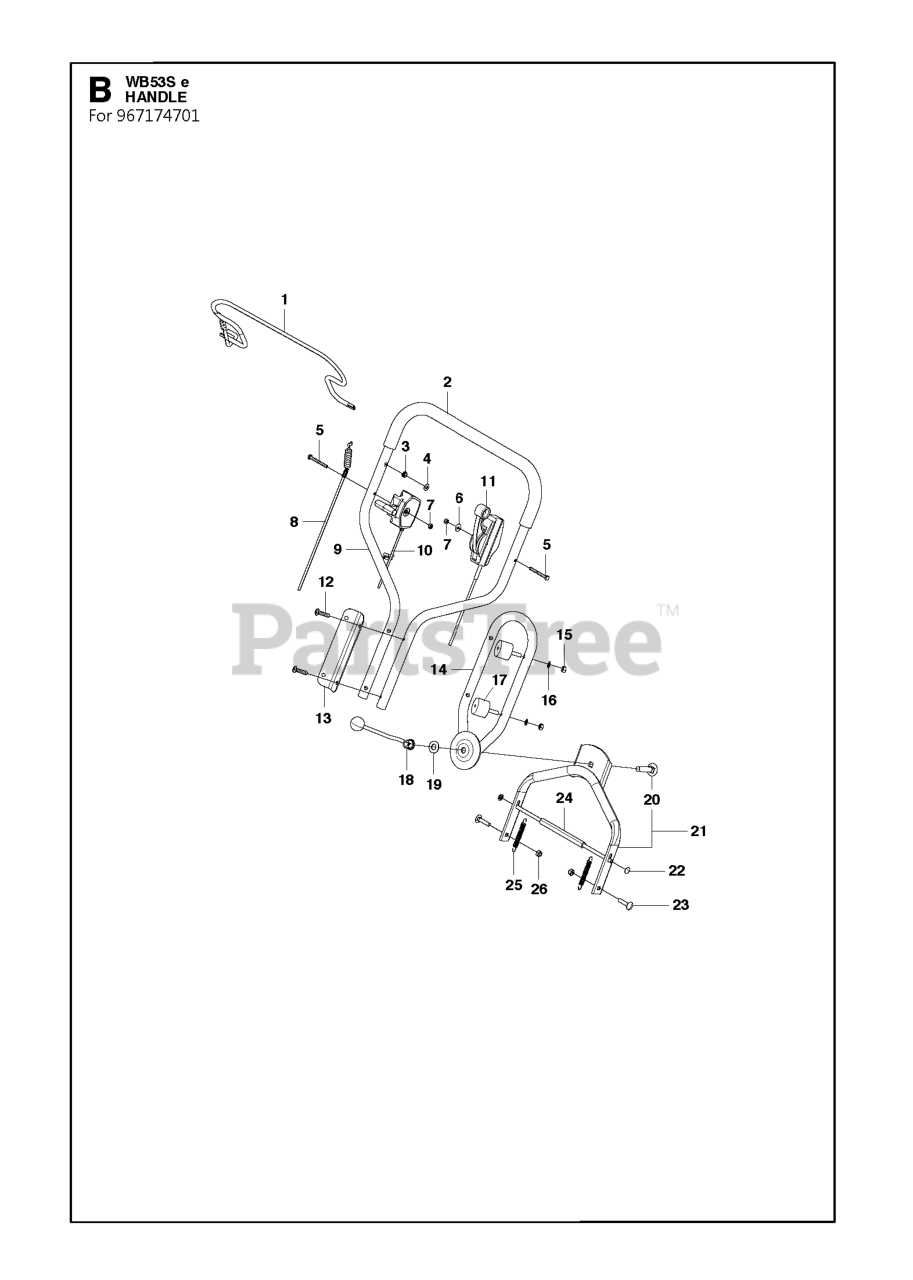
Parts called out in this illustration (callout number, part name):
5	SCREW M6X55
7	NUT FLANGE - M6
15	NUT
22	WASHER STARLOCK WITH CAP
26	NUT LOCK - M8, NYLOCK
